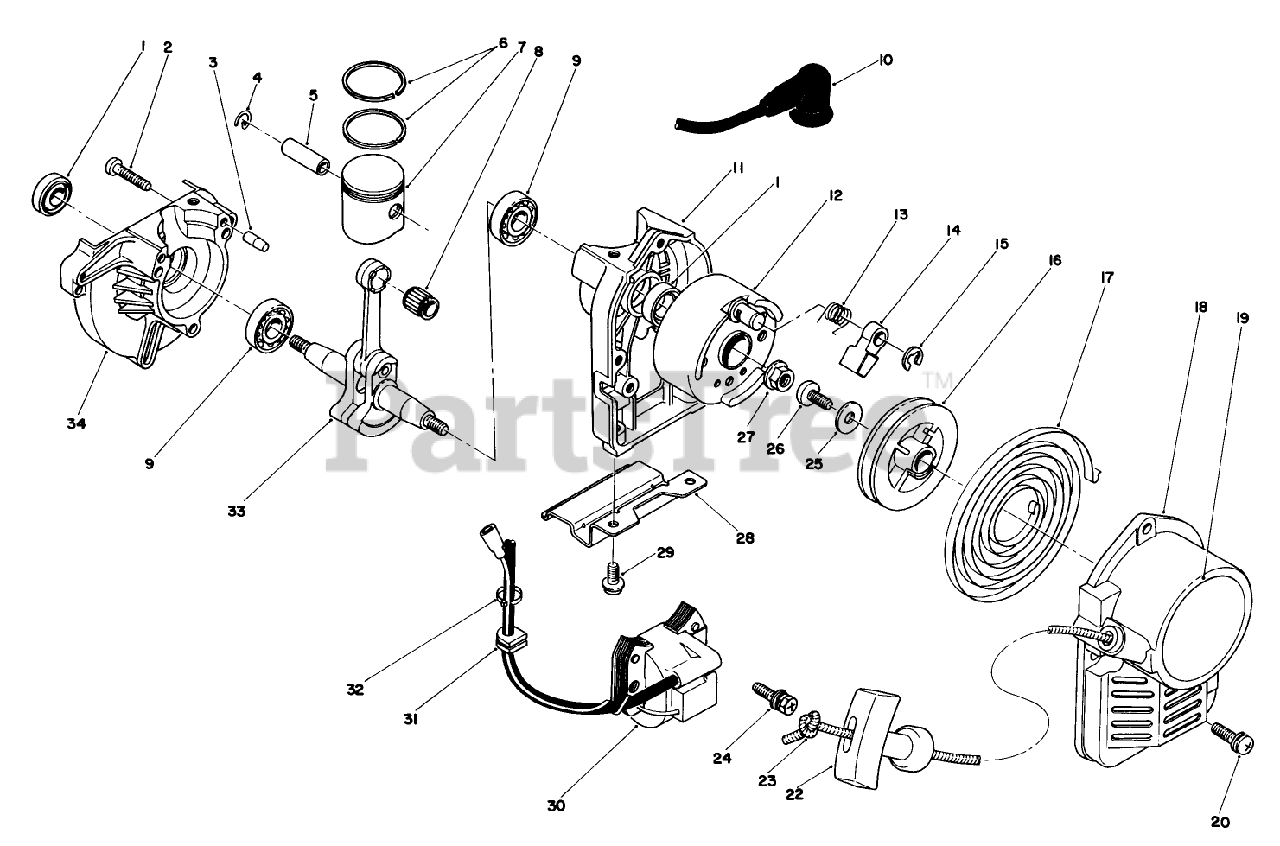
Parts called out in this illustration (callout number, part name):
1	OIL SEAL
4	PISTON PIN CLIP
6	PISTON RING
7	PISTON SET
9	BEARING
10	CAP-PLUG
20	SCREW & WASHER
